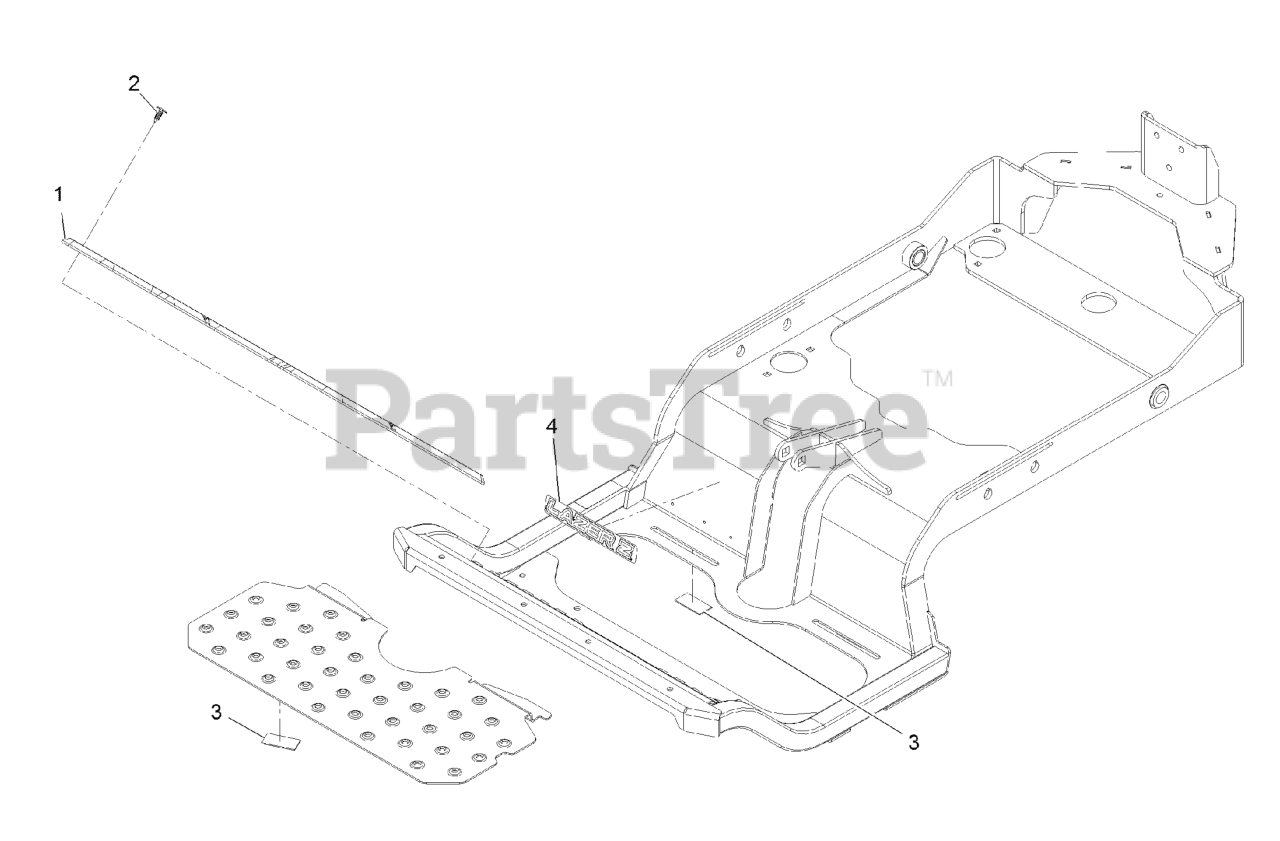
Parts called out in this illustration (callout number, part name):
1	FLOOR MAT
2	PLUG-PLASTIC
3	PAD-RUBBER
4	DECAL-LAZER LOGO
